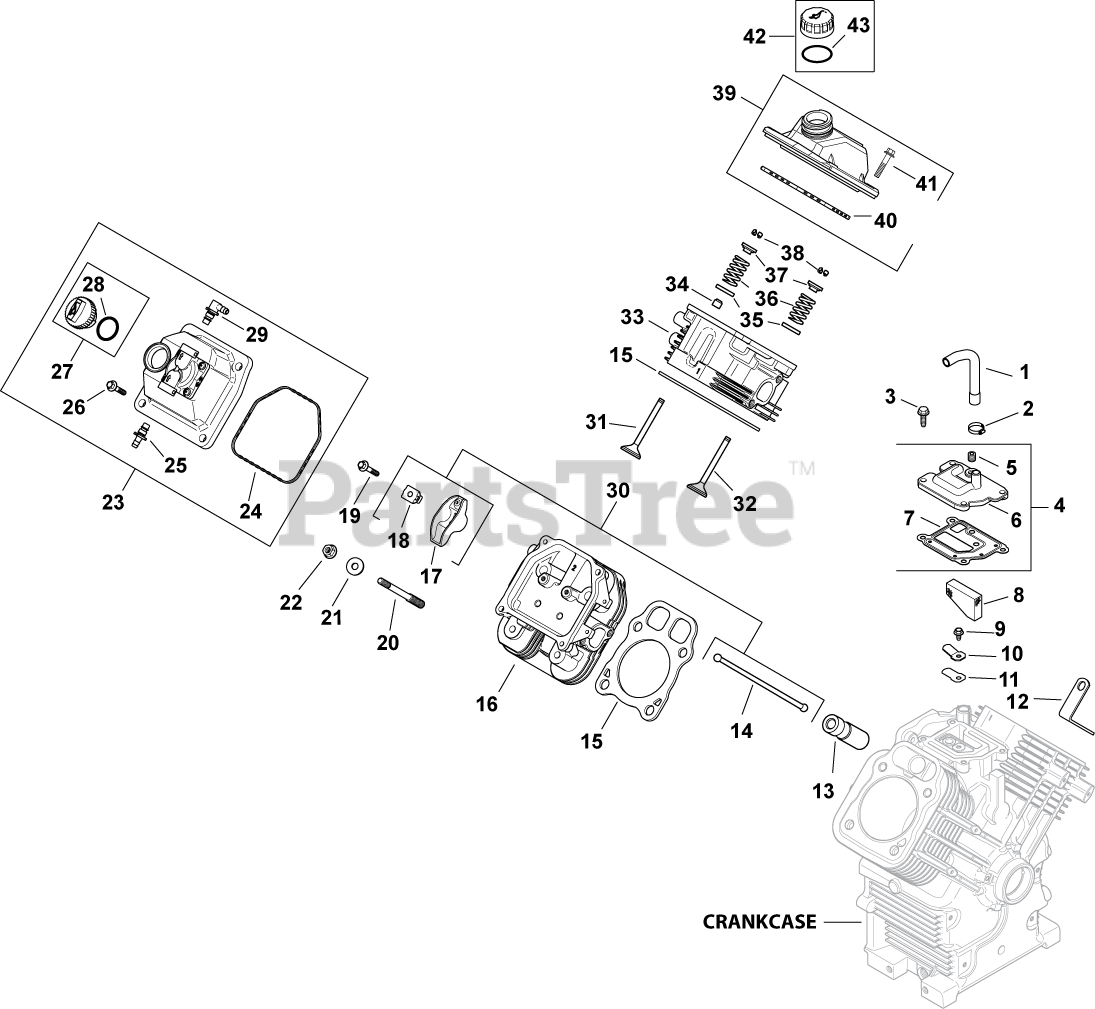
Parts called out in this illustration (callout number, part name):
1	HOSE, BREATHER
2	CLAMP, HOSE (KM)-USE 25 237 31-S
3	SCREW,FLG THD FRM M6X1.0X20-(#25086396S)
4	KIT, BREATHER ASSEMBLY
5	PLUG, CTSK PIPE 1/8"
6	COVER, BREATHER -USE 24 033 01-S
7	GASKET, BREATHER-USE 24 041 67-S
8	FILTER, BREATHER
9	SCREW, FLG THD FRM M5X.8X10
10	RETAINER, REED
11	REED, BREATHER
12	STRAP, LIFTING-USE 25 445 03-S
13	LIFTER, HYDRAULIC VALVE-USE 25 351 10-S
14	ROD, PUSH
15	CYL HEAD GASKET KIT-USE 24 841 04-S
16	HEAD, SERVICE ASSY CYL #2-USE 24 318 114
17	ARM, ROCKER
18	PIVOT, ROCKER ARM
19	SCREW, FLG M6X1.0X34
20	STUD, M8X1.25
21	WASHER, FLAT 8.6 MM
22	NUT, FLG M8X1.25
23	KIT, VALVE COVER-FUEL PUMP
24	O-RING (BLACK)
25	CONNECTOR
26	SCREW, FLG M6X1.0X30
27	CAP ASSY, OIL FILL (YELLOW)
28	O-RING-USE 24 153 32-S
29	CONNECTOR, 90 DEG. HOSE
30	KIT, VALVE TRAIN
31	VALVE, EXHAUST (STD) - USE 32 016 01-S
32	VALVE, INTAKE (STD)
33	HEAD, SERVICE ASSY CYL #1-USE 24 318 106
34	SEAL, VALVE STEM - (#2503214S)
35	RETAINER, SPRING
36	SPRING, VALVE
37	RETAINER, VALVE SPRING - USE 25 173 28-S
38	KIT, RETAINER
39	KIT, VALVE COVER-OIL FILL
40	O-RING (BLACK)
41	SCREW, SHOULDER
42	KIT, OIL FILL CAP (YELLOW)
43	O-RING, DIPSTICK
2401602-S	VALVE, EXHAUST (.25)
2401702-S	VALVE, INTAKE (.25)
